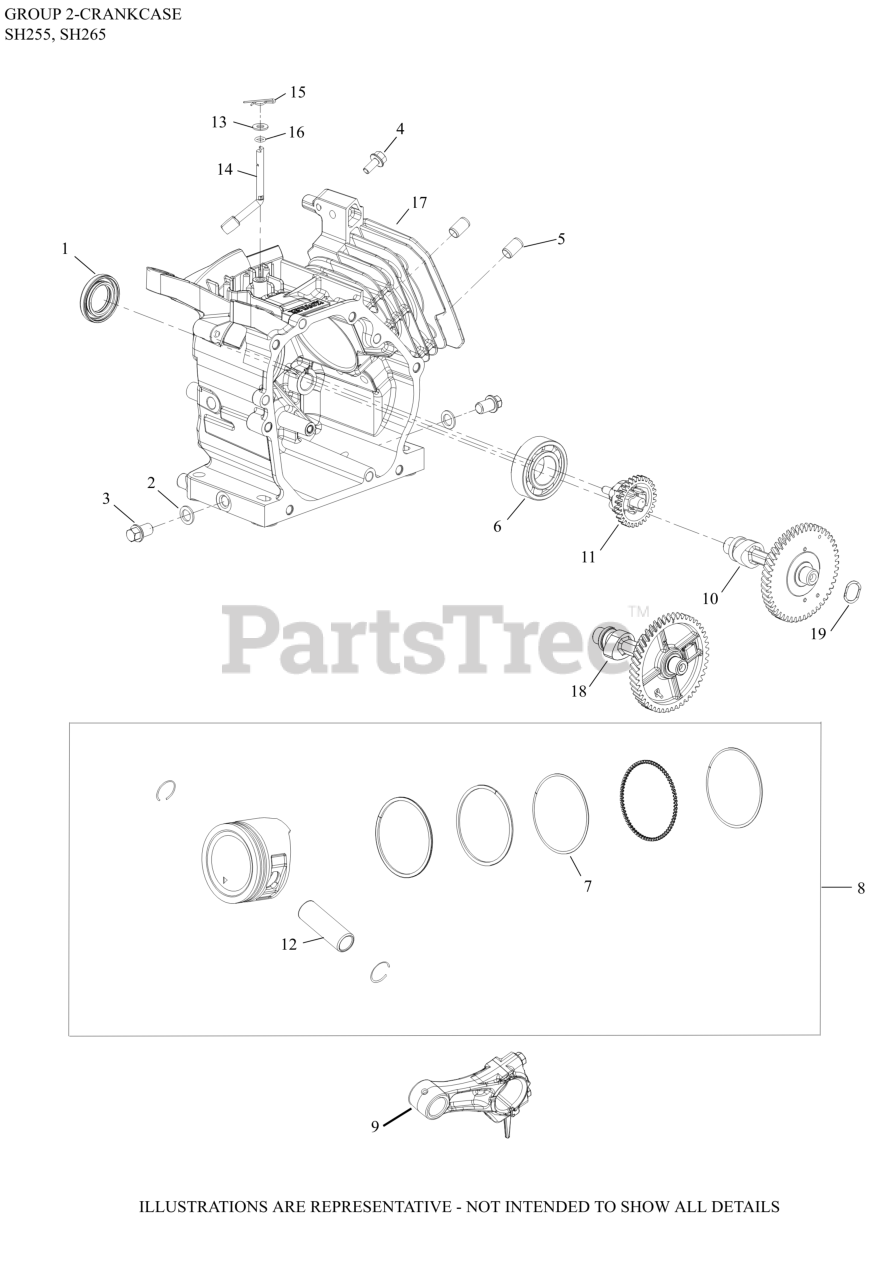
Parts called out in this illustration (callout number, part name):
1	SEAL - USE 17 032 29-S
2	WASHER, DRAIN PLUG
3	KIT, DRAIN PLUG
4	SCREW, HEX FLANGE (M6)-USE 25 086 433-S
5	PIN, DOWEL (8MM)
5	DOWEL, CYLINDER HEAD-(#1438013S)
6	BEARING, BALL
8	KIT, PISTON (STD)
9	ROD, CONNECTING ASSEMBLY
11	GOVERNOR ASSEMBLY
12	PIN, PISTON
13	WASHER, FLAT (DIA 13MM O.D.)-(#1446830S)
14	CROSS SHAFT
15	CLIP, GOVERNOR SHAFT
17	CRANKCASE
